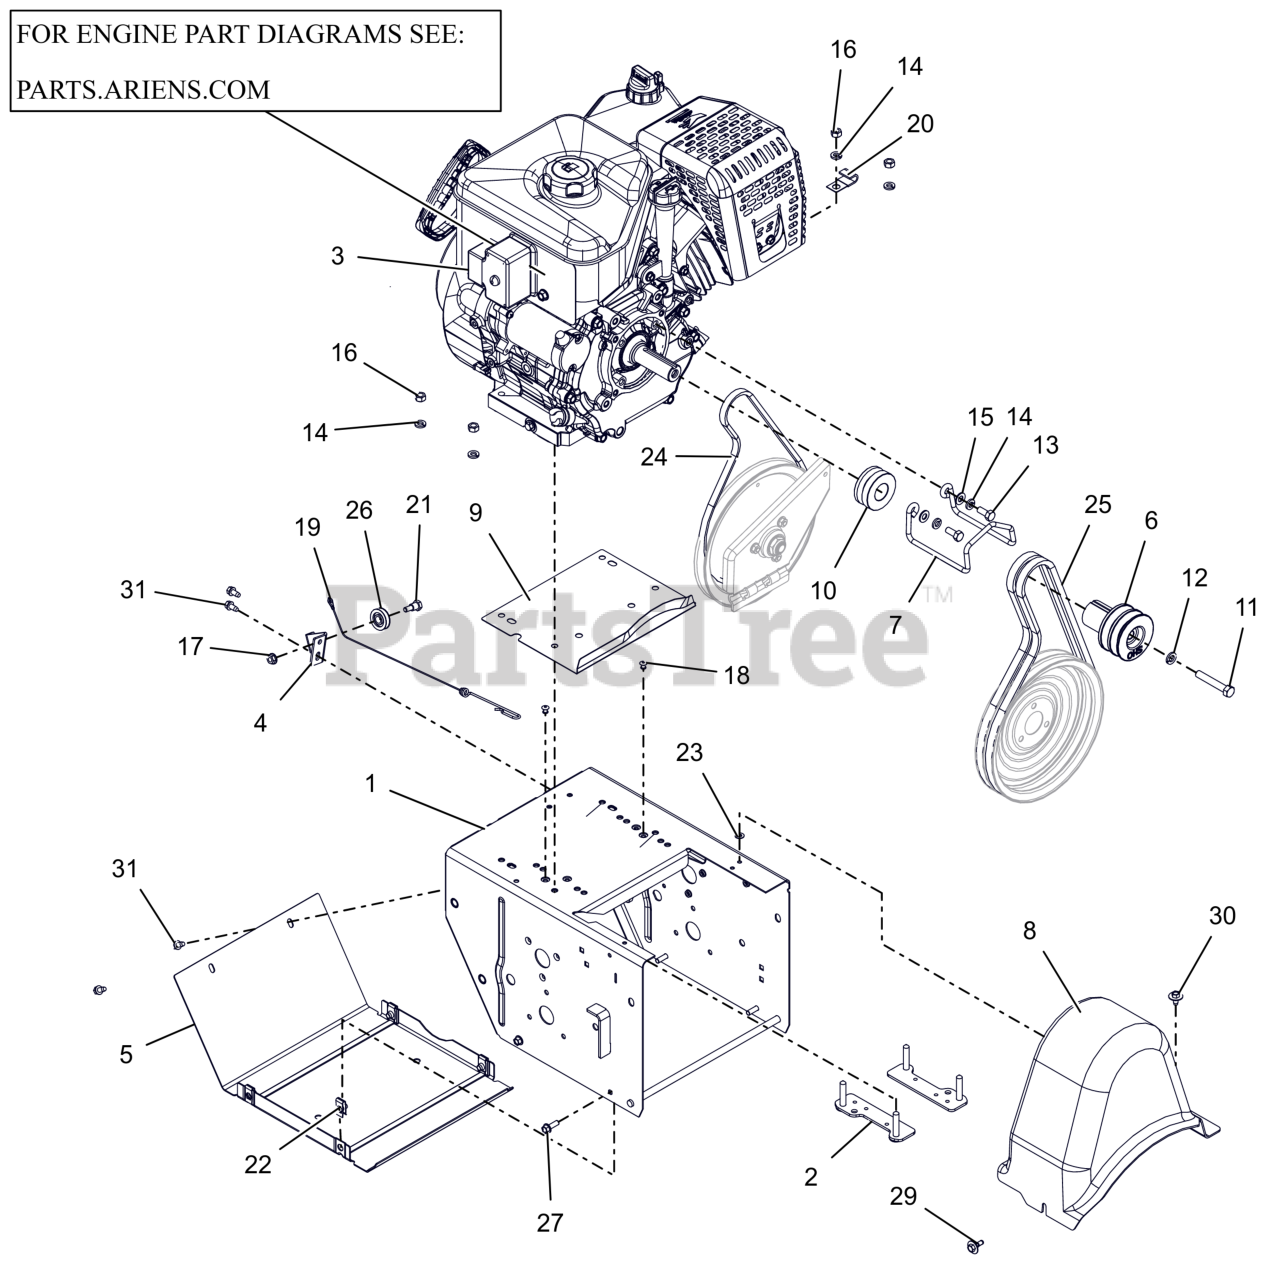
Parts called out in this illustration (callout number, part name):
1	FRAME, MAIN - 14GA DELUXE (ORANGE)
2	STRAP, BOLT-LARGE
3	ENGINE, AX369 GEN3 120V/60W
4	BRACKET, CABLE PULLEY
5	COVER, BOTTOM
6	SHEAVE,ATTACHMENT-SHO 2 GRV
7	FINGER, BELT
8	COVER, BELT-LARGE
9	BAFFLE, WATER - LARGE BLOCK
10	SHEAVE, TRACTION (KEYLESS)
11	BLT, HEX .38-24X2.25 G5 ZCC
12	WSHR,LK-REG .375X.094 ZCC
13	BLT, HEX .31-24X.750 G5 ZCC
14	WSHR, LK-HVY .312X.097 ZCC
15	WSHR,FLT .344X.688X.065 ZCC
16	NUT, HEX .312-18 ZCC
17	NUT-LK-TOP-FLG .250-20 GF ZCC
18	RVT, POP .1875 ZCC
19	CABLE, LOWER TRACTION,SS & PRO
20	J-CLAMP
21	BOLT, SHLDR -.375 X .375 X .25-20
22	NUT-RTNR .25-20X.56
23	NUT-PUSH .25X.50 O.D.
24	V-BELT, 3L-WRAPPED
25	V-BELT, HA-RAW EDGE (SET)
26	PULLEY, CABLE
27	BLT, HWH .25-20X.75 G5 ZCC
29	SCR-TAP .25-20X.5 CAPTIVE
30	SCR, TAP .25-20X.50 LG HWH ZCC
31	SCR-TAP .25-20X.50 HWH ZCC
